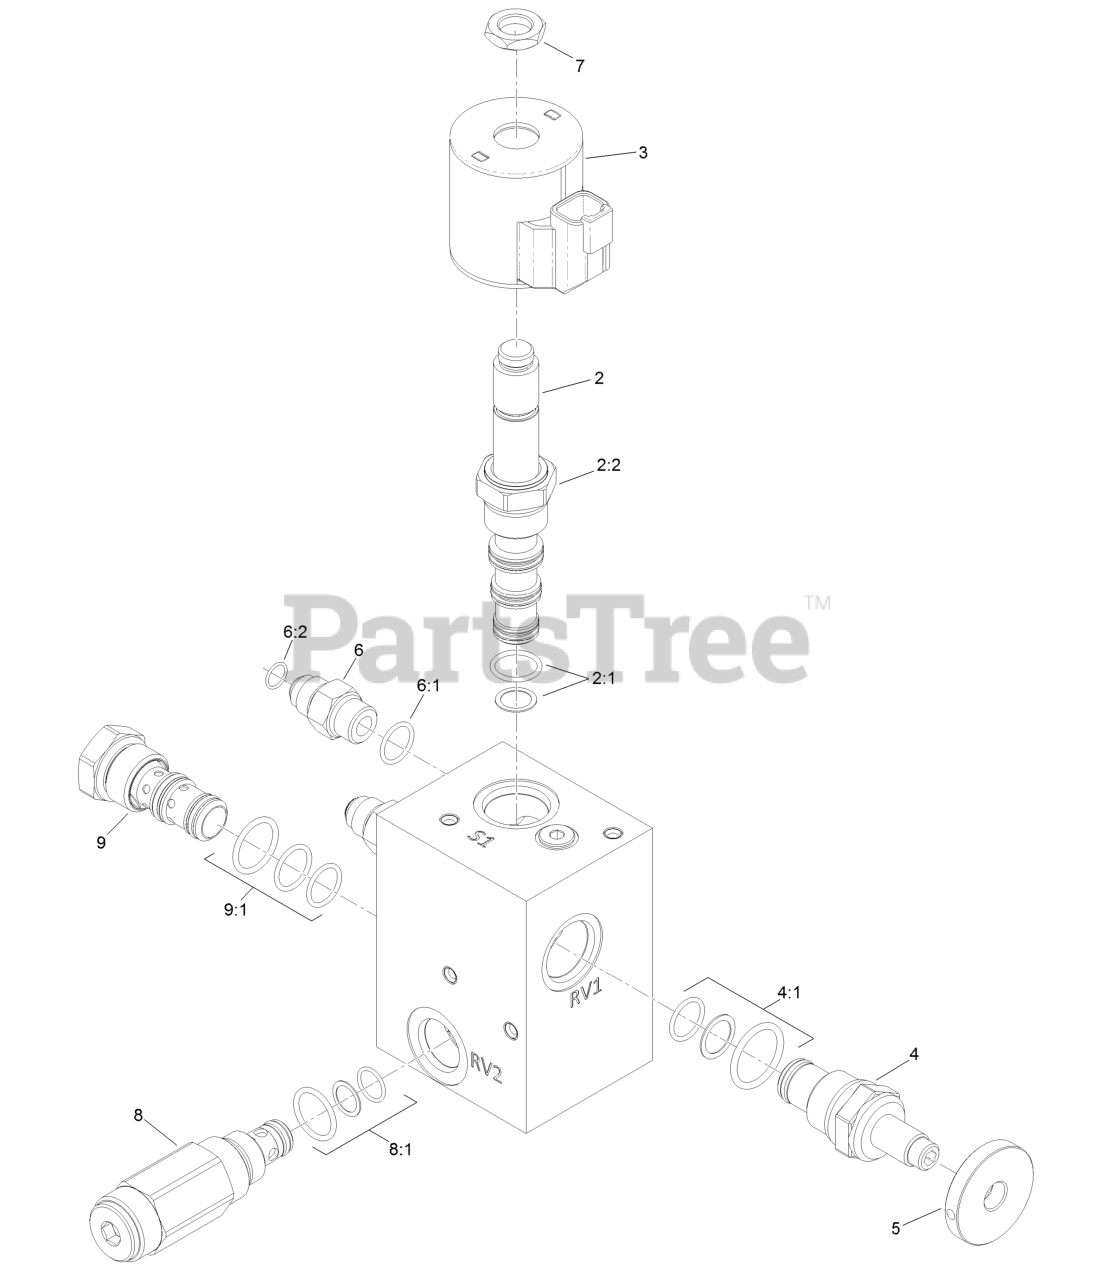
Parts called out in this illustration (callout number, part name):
2	Valve-Solenoid
2:1	Spool Valve Seal Kit
2:2	Nut-Coil
3	Coil-Solenoid
4	Valve-Relief, Poppet Style
4:1	Relief Valve Seal Kit
5	Knob (1.5 DIA)
6	Fitting-Straight
6:1	O-Ring
7	Nut-Coil
8	Valve-Relief
8:1	Seal Kit
9	Valve-Check, P O
9:1	Seal Kit
